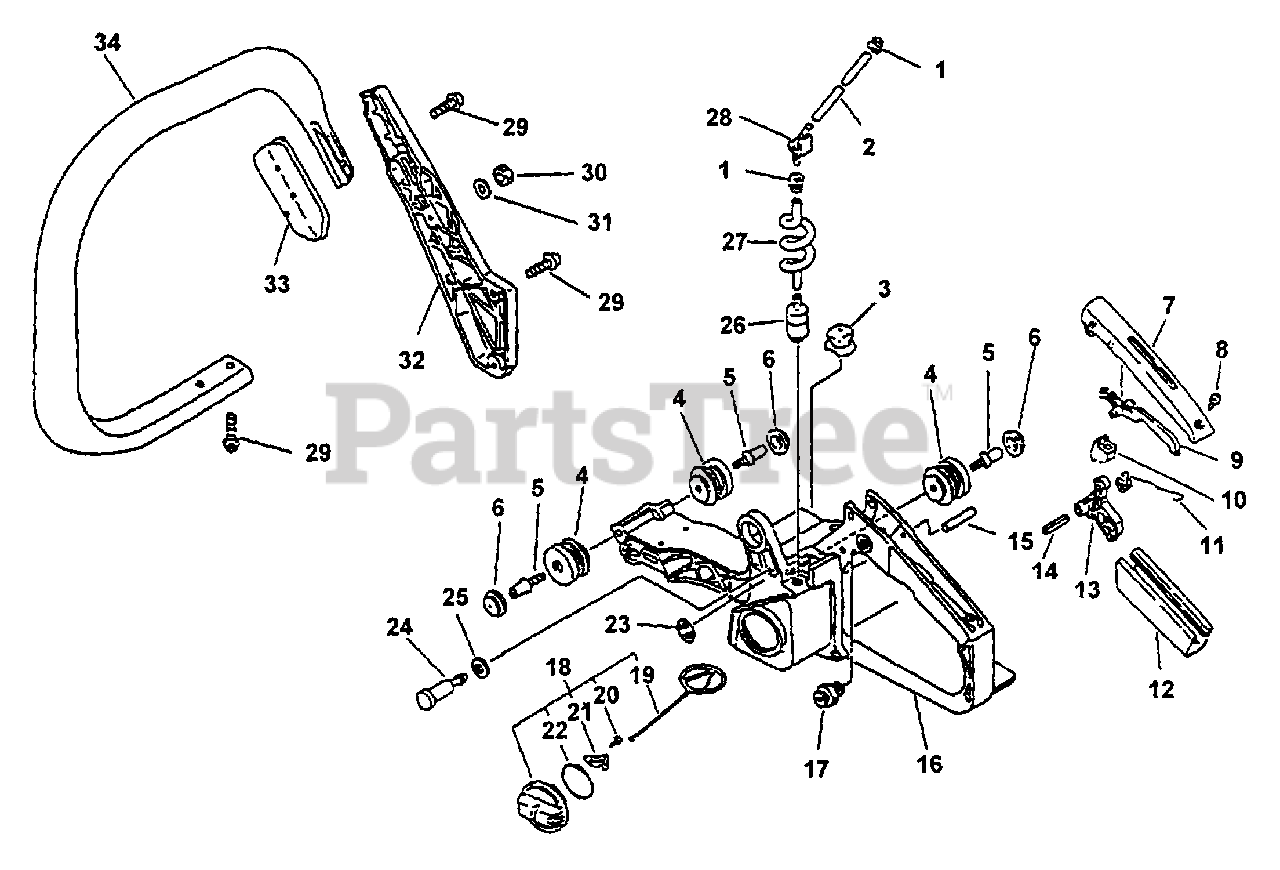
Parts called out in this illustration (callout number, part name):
1	GROMMET
2	PIPE - 3X6X100 -- BLACK
4	CUSHION
6	CAP, CUSHION
7	COVER, HANDLE
8	SCREW - 4X14
9	LEVER, TRIGGER LOCKOUT
11	SPRING, TRIGGER
12	GRIP, HANDLE
13	TRIGGER, THROTTLE
14	PIN - SPRING -- 5X25
15	PIN - 3X26
16	HANDLE - REAR
17	LOCK, THROTTLE
18	CAP ASSY
19	CONNECTOR, CAP
20	SCREW - 3X8
21	RETAINER
22	O-RING - 29
24	VENT, FUEL TANK
25	GROMMET
26	FILTER, FUEL
27	PIPE, FUEL - SPIRAL
28	CONNECTOR, PIPE
29	SCREW - 5X20 -- TAPPING
30	NUT - 5 -- SLOTTED
31	WASHER - 5
32	BRACKET, HANDLE - OUTER
33	BRACKET, HANDLE
34	HANDLE - FRONT
